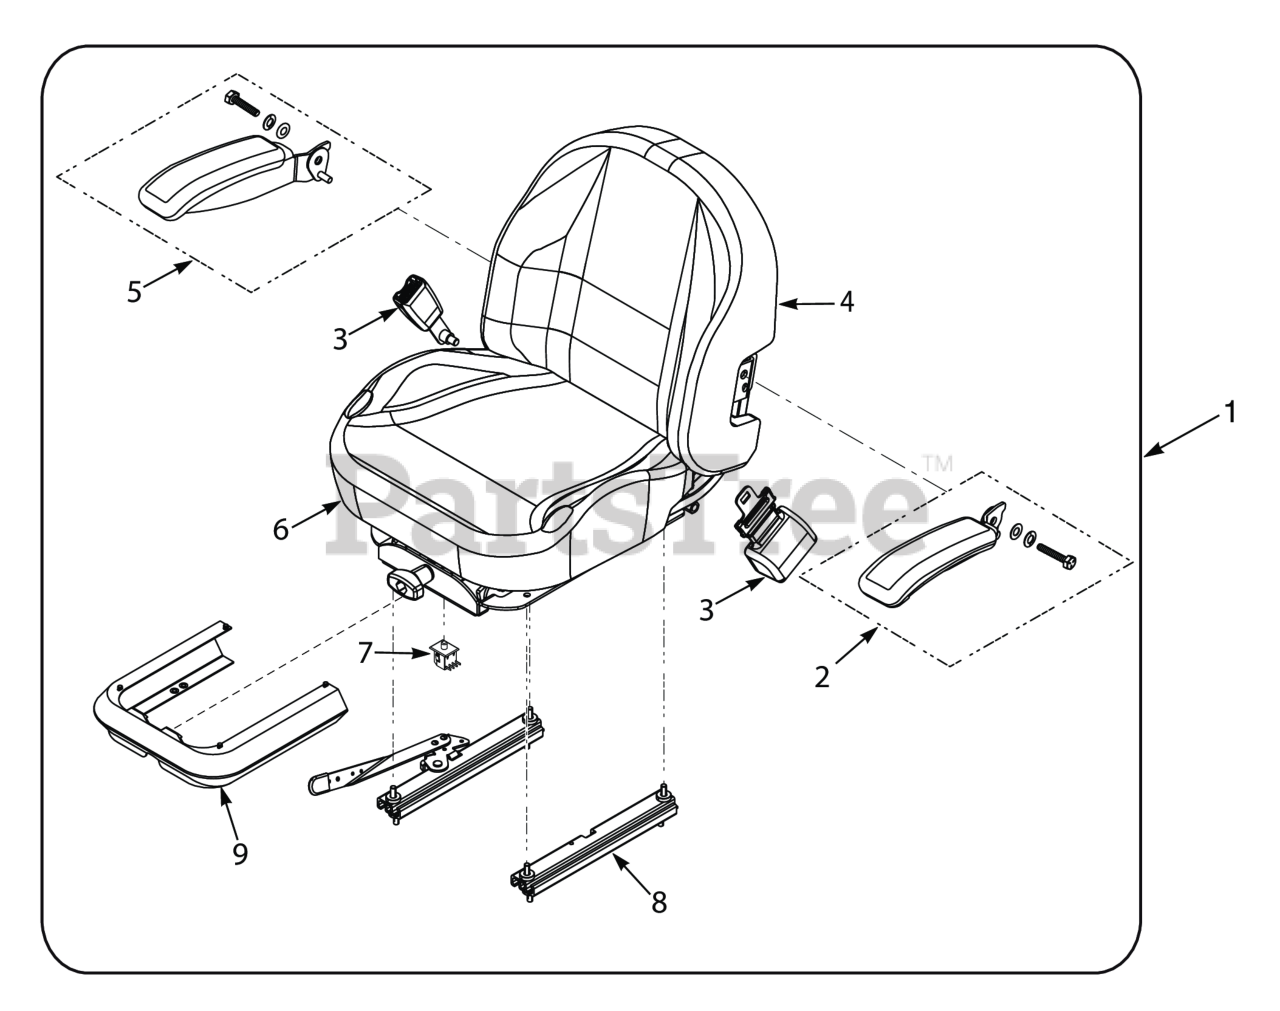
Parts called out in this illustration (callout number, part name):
1	Seat Assembly
2	Armrest Kit, LH
3	Seatbelt Kit
4	Back Cover
5	Armrest Kit, RH
6	Cushion Cover
7	Switch, Double Pole - Plunger
8	Track Set
9	Bellows, Seat
